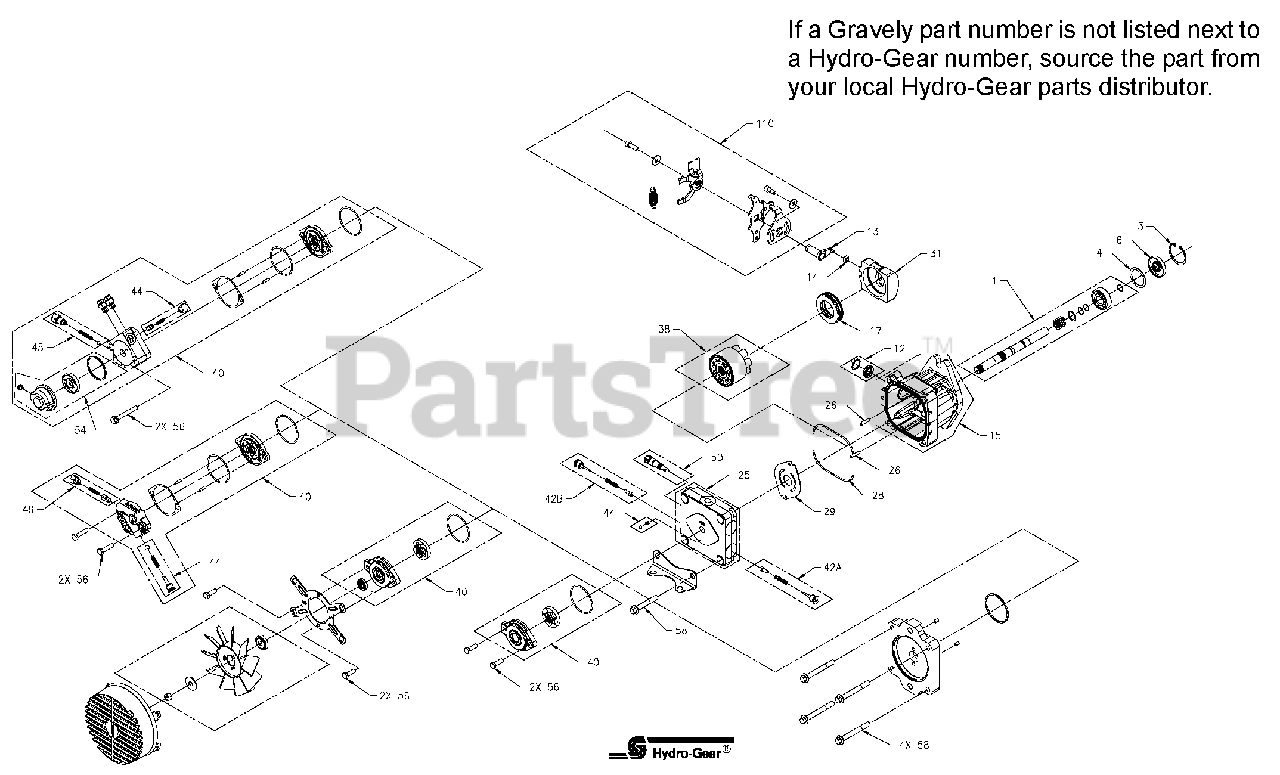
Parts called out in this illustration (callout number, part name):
1	Kit, Input Shaft
3	Ring, Retaining
4	Washer, 1.45 x 1.84 x .04
6	Lip Seal, 17 x 47 x 8
12	Kit, Trunnion Seal
13	Trunnion Arm, Taper Square
14	Slot Guide
15	Kit, Housing
17	Assembly, Thrust Ball Bearing
25	Kit, Encap
26	Pin
28	O-Ring
29	Valve Plate
31	Variable Swashplate
38	Kit, Cylinder Block
40	Kit, Auxiliary Pump
42	Kit, Shock Valve
44	Kit, Charge Relief
45	Kit, Auxilary Relief Valve
50	Kit, Bypass Valve
54	Kit, Auxilary Filter Kit
56	Screw, 5/16-18 x 1
58	Kit, HSG Bolt
110	Kit, Return
